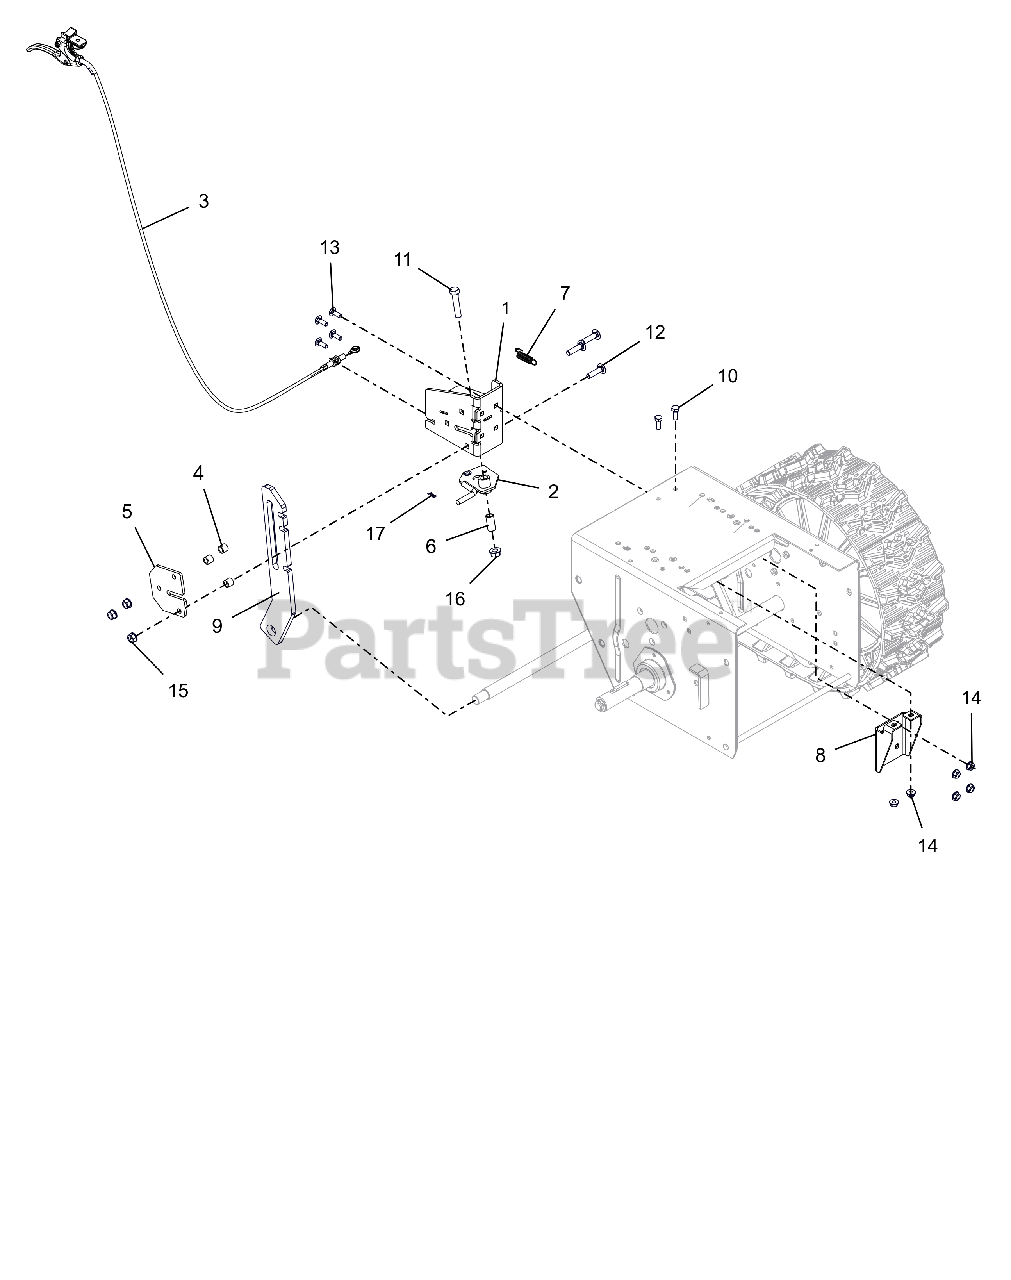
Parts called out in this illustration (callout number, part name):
1	BRACKET,HEIGHT ADJUSTER-DELUXE
2	LOCK,HEIGHT ADJUSTER TRIGGER
3	CABLE, TRACK REMOTE
4	SPACER .50 X .32 X .42
5	PLATE, HEIGHT ADJUSTER
6	BSHG-SLV .385X.500X1.045
7	SPRING-EXT .047 X .438 X 1.85
8	BRACKET, REINFORCEMENT
9	ADJUSTER, HEIGHT-DELUXE BWT
10	BLT, HEX .25-20X.75 G5 ZCC
11	BLT, HEX .38-16X1.75 G5 ZCC
12	BLT, RHSSN.31-18X1.25 G5 ZCC
13	BLT, RHSN .25-20X.750 G5 ZCC
14	NUT-LK-CTR-FLG .25-20 ZC120
15	NUT-LK-TOP-FLG .312-18 GF ZCC
16	NUT-LK-CTR-FLG .375-16 GF ZCC
17	PIN, HAIR #178 .06X.77 ZCC
